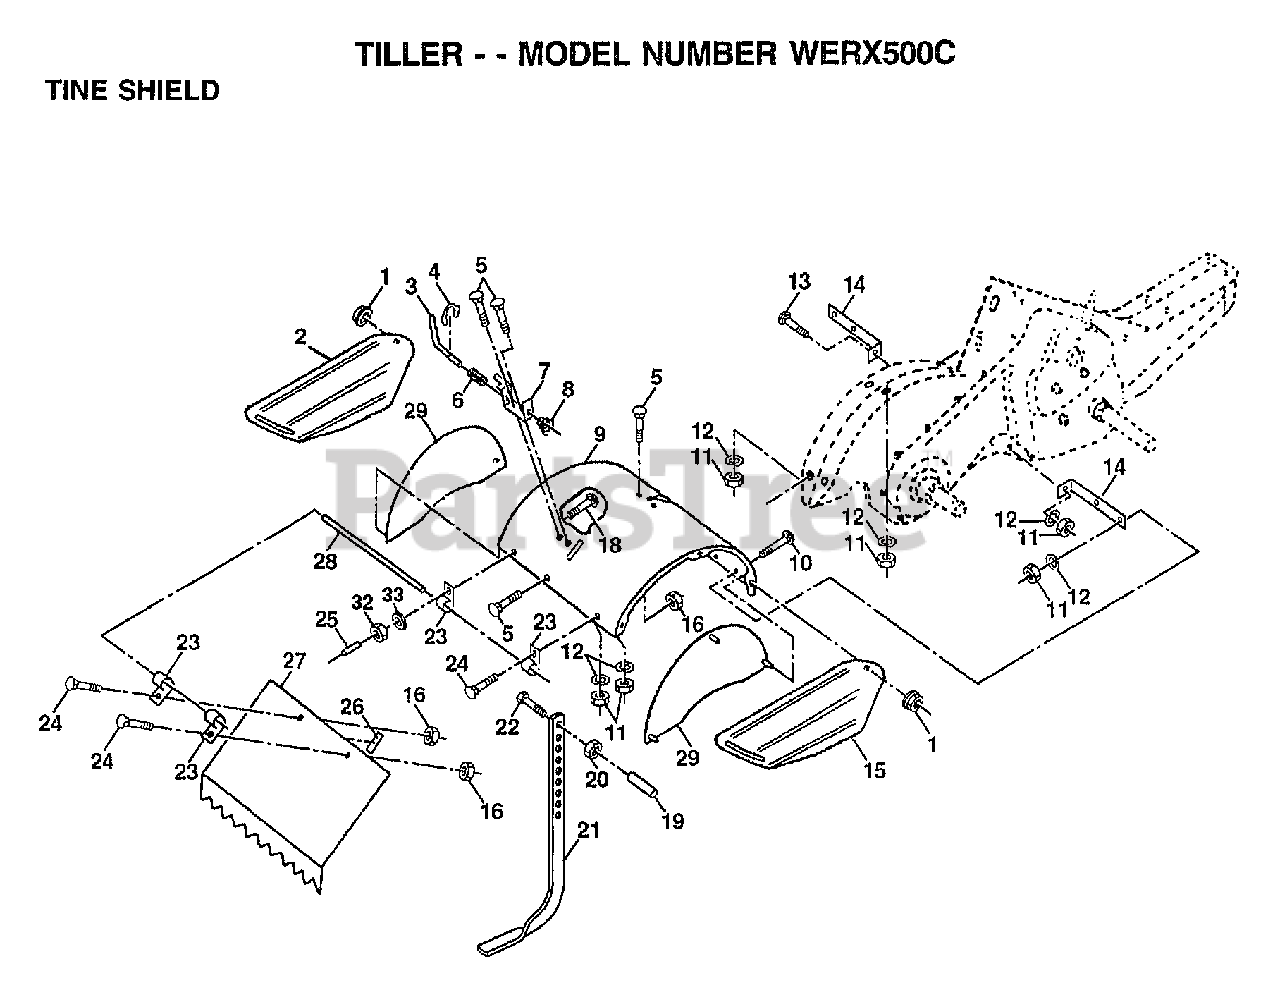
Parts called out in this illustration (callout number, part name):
1	"NUT HEX,LOCK,FLAN"
2	SHIELD.SIDE.OUTER.LH
3	STAKE PIN TI
4	KLIP RING TI
5	BOLT
6	SPRING TI
7	LATCH BRACKET TI
8	SPRING CRT
9	SHIELD.TINE
10	BOLT
11	NUT.HEX.5/16-18
12	LOCKWASHER
13	BOLT
14	"BRACKET,SHIELD"
15	SHIELD.SIDE.OUTER.RH
16	NUT T
18	BOLT
19	GRIP CRT
20	NUT.HEX.3/8-16UNC
22	BOLT
23	HINGE CRT
24	BOLT
25	VINYL CAP TI
26	PAD IDLER TI
27	SHIELD.LEVELING
28	PIN HINGE
30	LOCKNUT TI
33	LOCKWASHER
